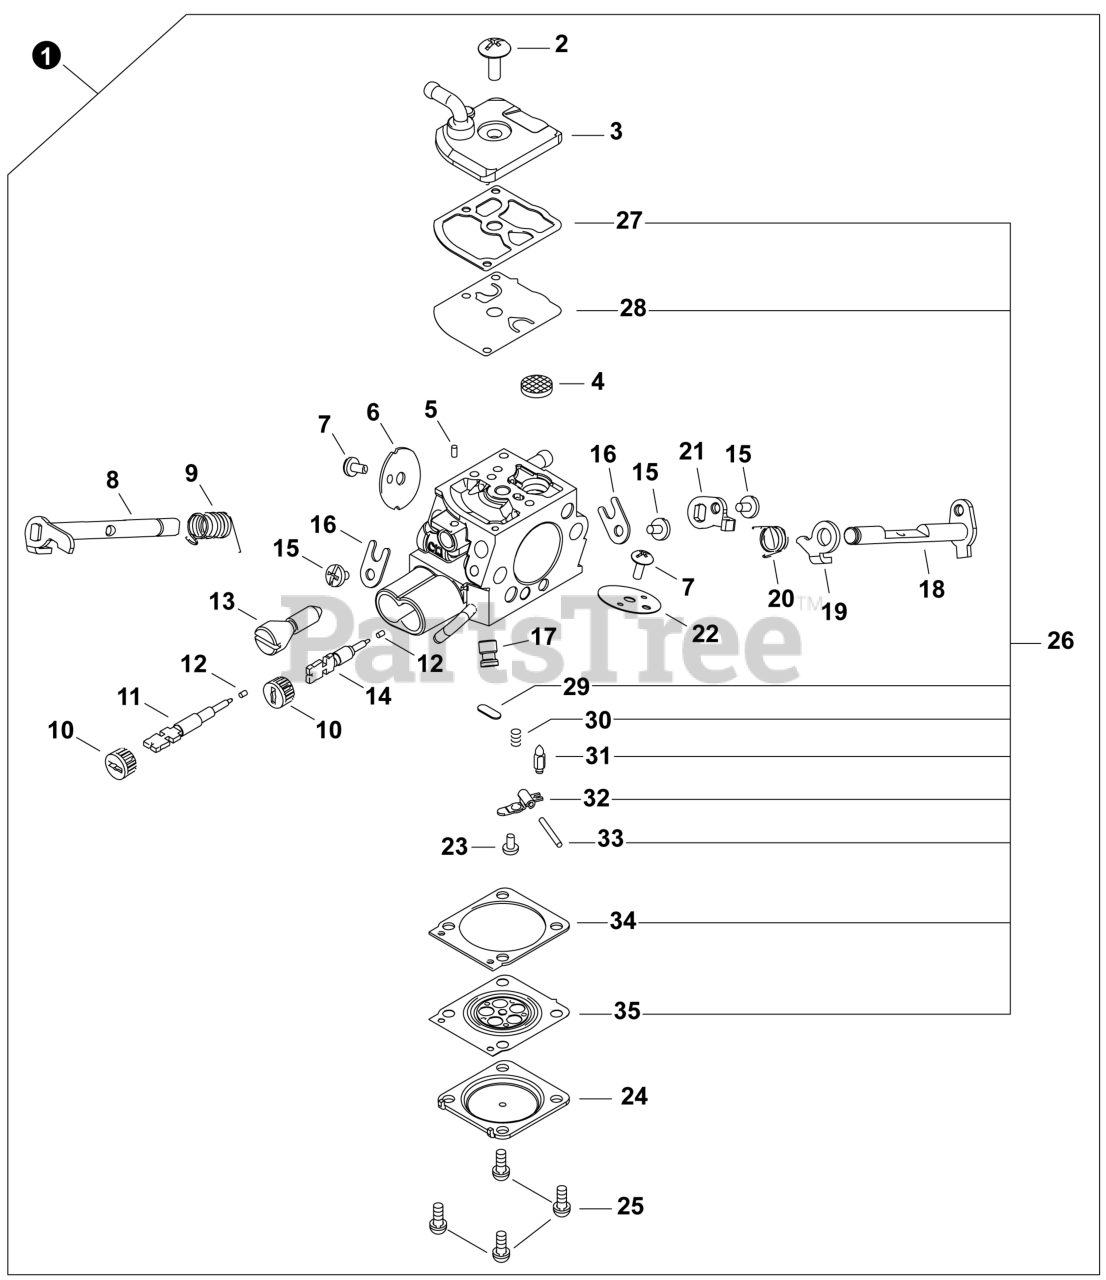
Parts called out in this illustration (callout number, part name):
1	CARBURETOR - Z011-72G
2	SCREW
3	COVER, PUMP
4	SCREEN, FUEL INLET
5	PIECE, FRICTION
6	VALVE, THROTTLE
7	SCREW 3x4.5
8	SHAFT ASSY, THROTTLE
9	SPRING, RETURN
10	CAP, LIMITER
11	SCREW, IDLE ADJUST
12	RETAINER
13	SCREW, THROTTLE ADJUST
14	SCREW
15	SCREW
16	CLIP, THROTTLE SHAFT
17	NOZZLE, CHECK VALVE
18	SHAFT ASSY, CHOKE
19	LEVER, CHOKE
20	SPRING, RETURN
21	LEVER, THROTTLE
22	VALVE, CHOKE
23	SCREW
24	COVER, METERING DIAPHRAGM
25	SCREW
26	REPAIR KIT, CARBURETOR
27	GASKET, PUMP
28	DIAPHRAGM, PUMP
29	PLUG, WELCH
30	SPRING, COIL
31	VALVE, INLET NEEDLE
32	LEVER, METERING
33	PIN, METERING LEVER
34	GASKET, METERING DIAPHRAGM
35	DIAPHRAGM, METERING
